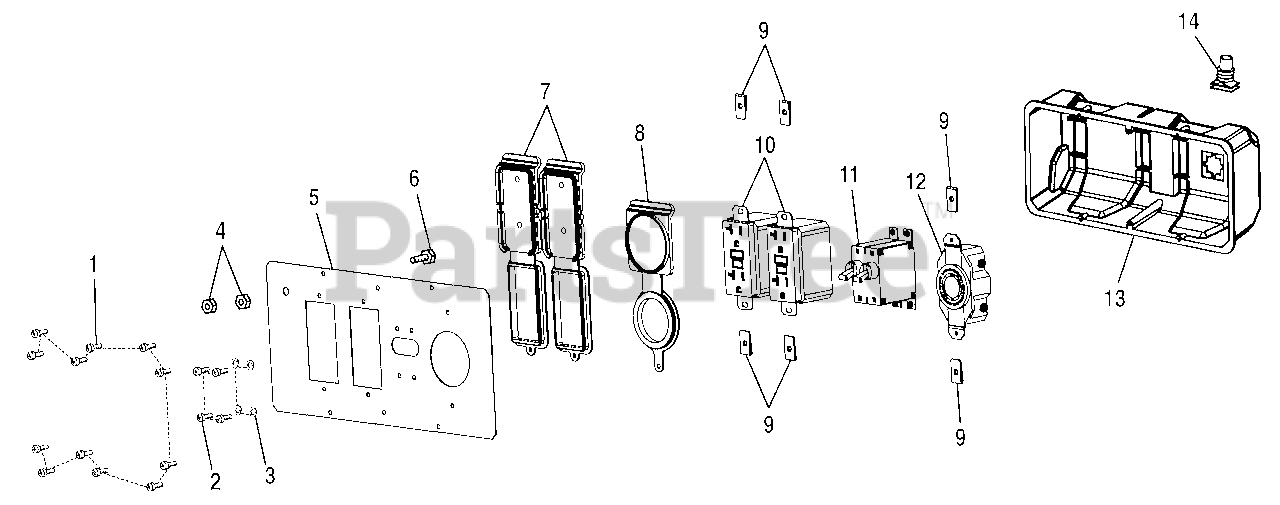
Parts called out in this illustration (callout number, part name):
1	SCREW (6-20 X 3/8 IN.)
2	SCREW (M3 X 6)
3	LOCK WASHER
4	HEX NUT (1/4-20)
5	COVER PLATE
6	SCREW (1/4-20 X 5/8 IN HEX HD)
7	OUTLET COVER (120 VOLT)
8	OUTLET COVER (240 VOLT)
10	DUPLEX RECEPTACLE (120 VOLT)
11	CIRCUIT BREAKER(20AMP 125VOLT)
12	TWST LCK RECEPT 120/240VLT 20A
13	REAR CONTROL PANEL
14	RUBBER BOOT
